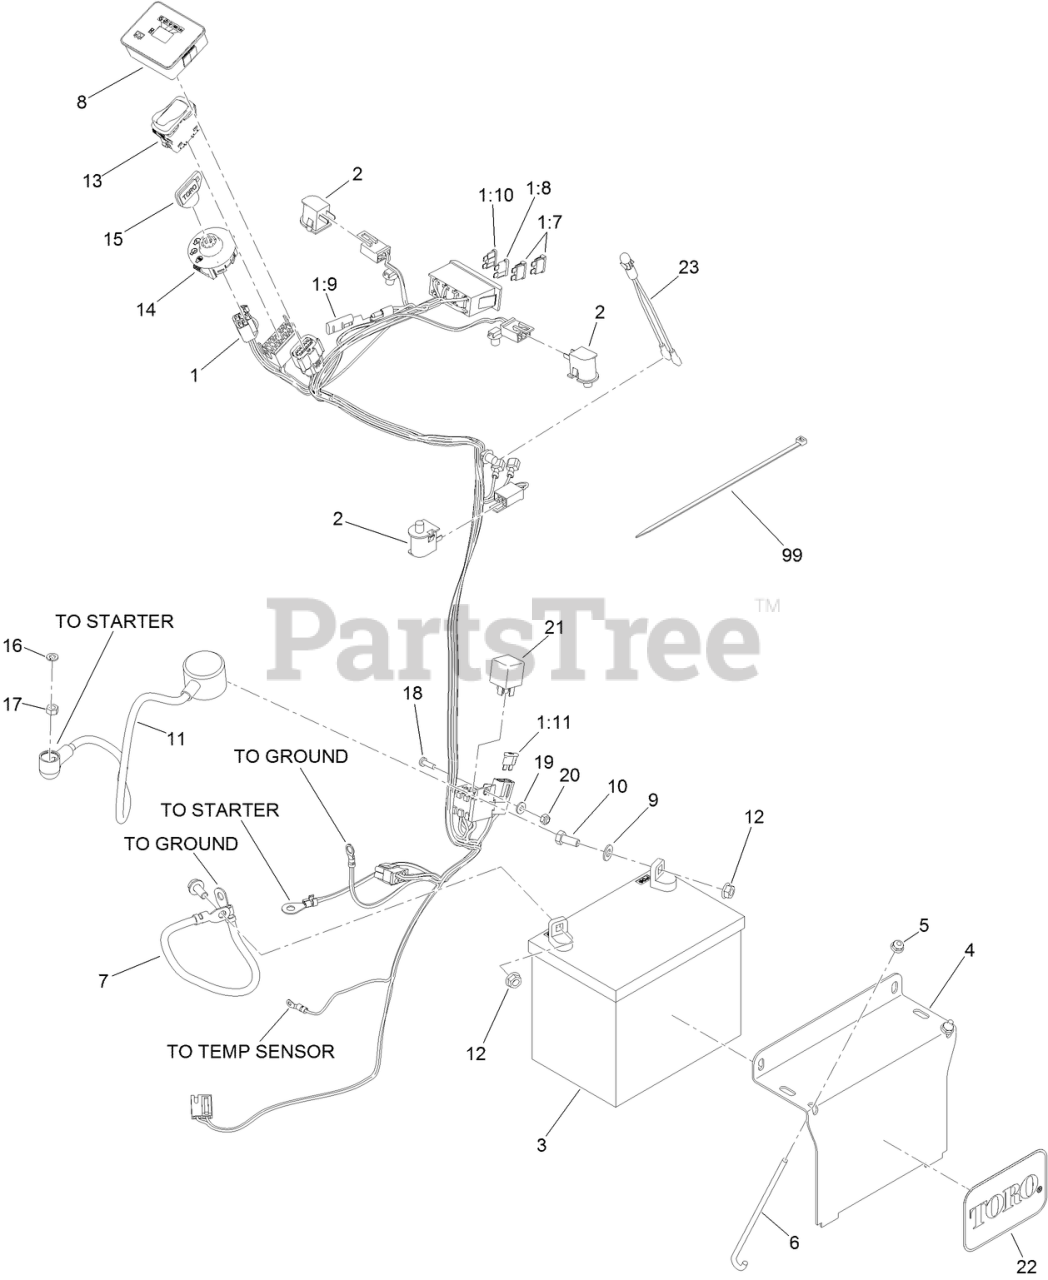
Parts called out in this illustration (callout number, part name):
1	HARNESS-WIRE, GRANDSTAND
1:7	FUSE-BLADE, 15 AMP
1:8	FUSE-BLADE, 10 AMP
1:9	CAP-PLUG
1:10	FUSE-BLADE, 7.5 AMP
1:11	FUSE-BLADE, 20 AMP
2	SWITCH-BAIL
3	BATTERY-DRY
4	BRACKET-HOLD DOWN, BATTERY
5	NUT-HF
6	BOLT-HOLDDOWN
7	CABLE-BATTERY, BLACK
8	MODULE-METER, HOUR
9	WASHER-PLAIN
10	SCREW-HH
11	CABLE-BATTERY, POSITIVE
12	NUT-HHF, SMOOTH
13	SWITCH-ROCKER, (ON)-ON-OFF
14	SWITCH-IGNITION
15	KEY-IGNITION
16	WASHER-LOCK
17	NUT-HEX
18	SCREW-PPH
19	WASHER-FLAT
20	NUT-LOCK, NI
22	DECAL
23	INDICATOR-LED, RED
99	TIE-CABLE
